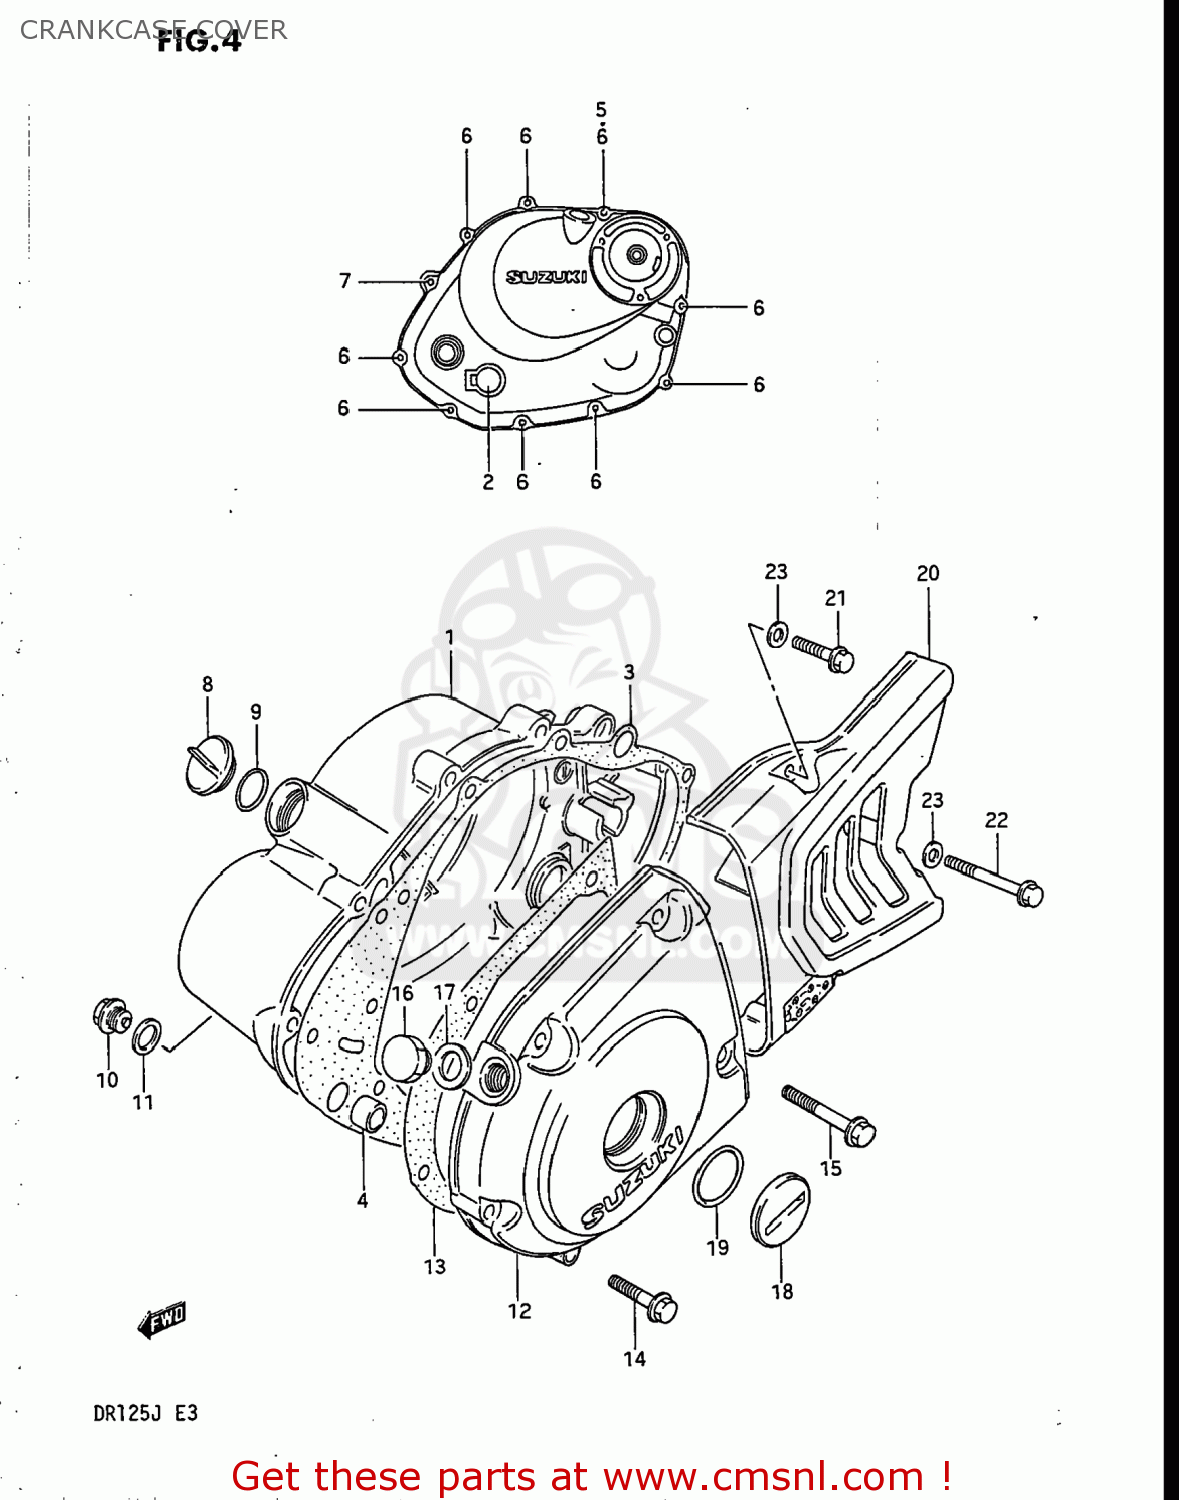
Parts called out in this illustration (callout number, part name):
1	COVER,CLUTCH
2	LENS,OIL LEVEL CHECK
3	GASKET,CLUTCH COVER (MCA)
4	PIN
5	WASHER
6	BOLT 6X30
7	BOLT
8	PLUG
9	O RING(D:3.1,ID:16.8)
10	PLUG(14X12)
11	GASKET(14X19.2X2) (NAS)
12	COVER,MAGNETO
13	GASKET,MAGNETO COVER (MCA)
14	BOLT 6X30
15	BOLT 6X40
16	PLUG(12X9)
17	GASKET(12.1X16.2X3.7) (NAS)
18	PLUG
19	O RING(D:3.1,ID:22.7)
20	COVER,ENGINE SPROCKET
21	BOLT
22	BOLT
23	WASHER,5MM
